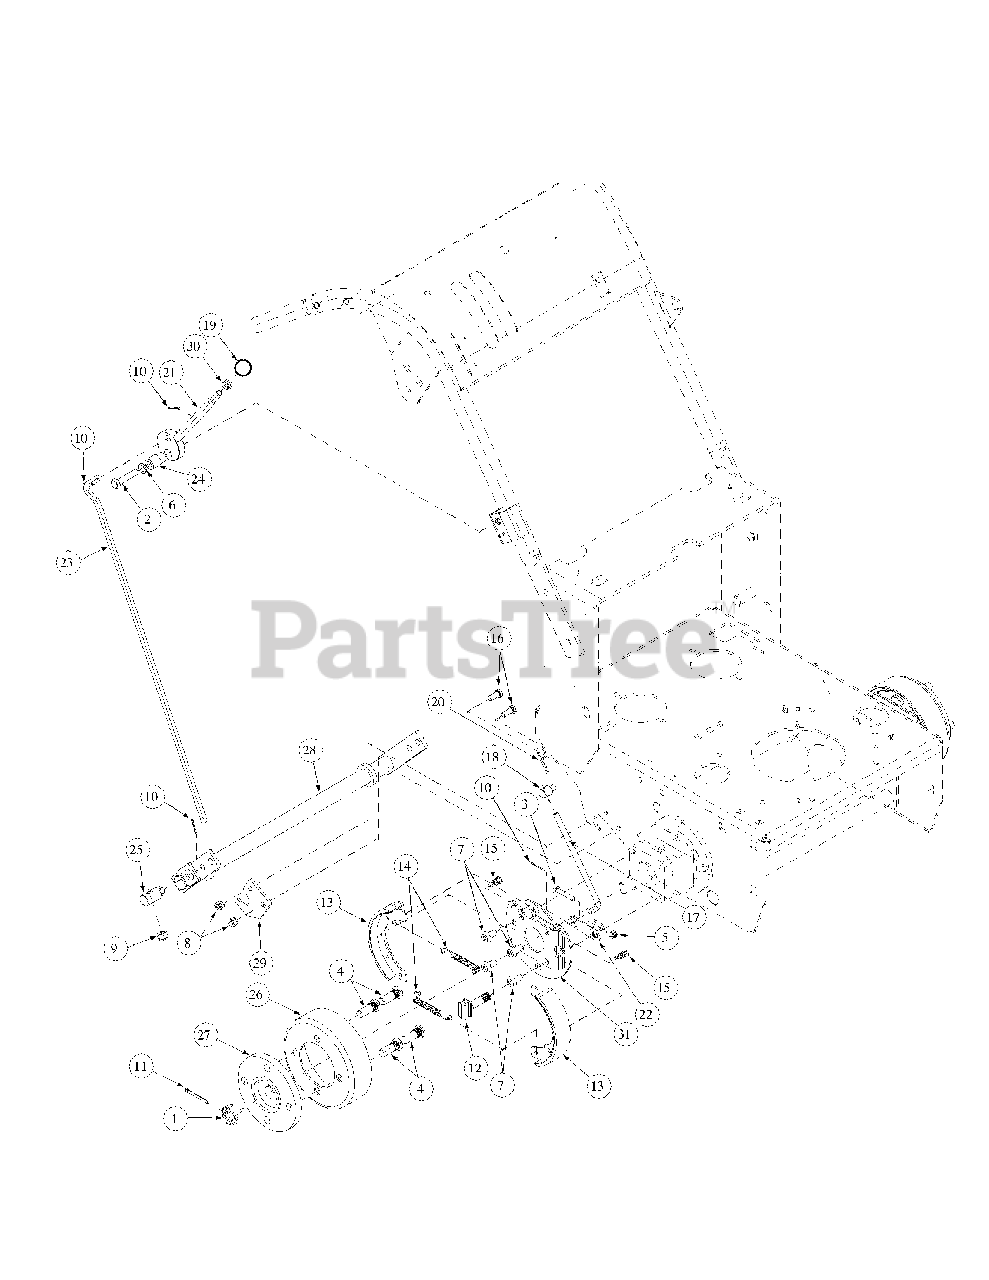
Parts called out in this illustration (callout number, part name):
1	Nut, Castle, 3/4-16
2	Capscrew, 3/8-16 x 1" Grade 5 Zinc
3	Cap Screw, 1/4-20 x 1.50, Grade 5
4	Bolt, Wheel, 1/2-20 x 1-3/8
5	Lock Nut, Nylon Insert, 1/4-20 Grade A
6	Lock Washer, 3/8 Zinc
7	Capscrew, Socket Button Hd., 3/8-16 x 3/4 Zinc
8	Nut, 5/16-18, Nylock
9	Nut, Nylon Insert, 3/8-16 Grade A
10	Cotter Pin, 3/32 x 3/4, Zinc
11	Cotter Pin, 5/32 x 1-1/2 Zinc
12	Brake Cam, Actuating
13	Brake Shoe w/Lining, 6 x 1-1/4
14	Brake Spring, Tension
15	Brake Spring, Anti-Vibration
16	Cap Screw, 5/16-18 x 3/4, Grade 5
17	Brake Rod
18	Swivel Joint
19	Red Knob, Shift w/Insert
20	Hair Pin 3/8"-1/2"
21	Lever Assembly, Brake
22	Brake Clamp, Control Assembly Hydro
23	Rod, Long Brake, Hydro WB
24	Pivot Spacer, Hydro WB
25	Brake Pull Joint
26	Brake Drum
27	Hub, Wheel Motor
28	Brake Pivot Shaft Assembly
29	Pivot Mount, Brake
30	Nut, 3/8-16, Jam, Grade 2
31	Brake Backing Plate
